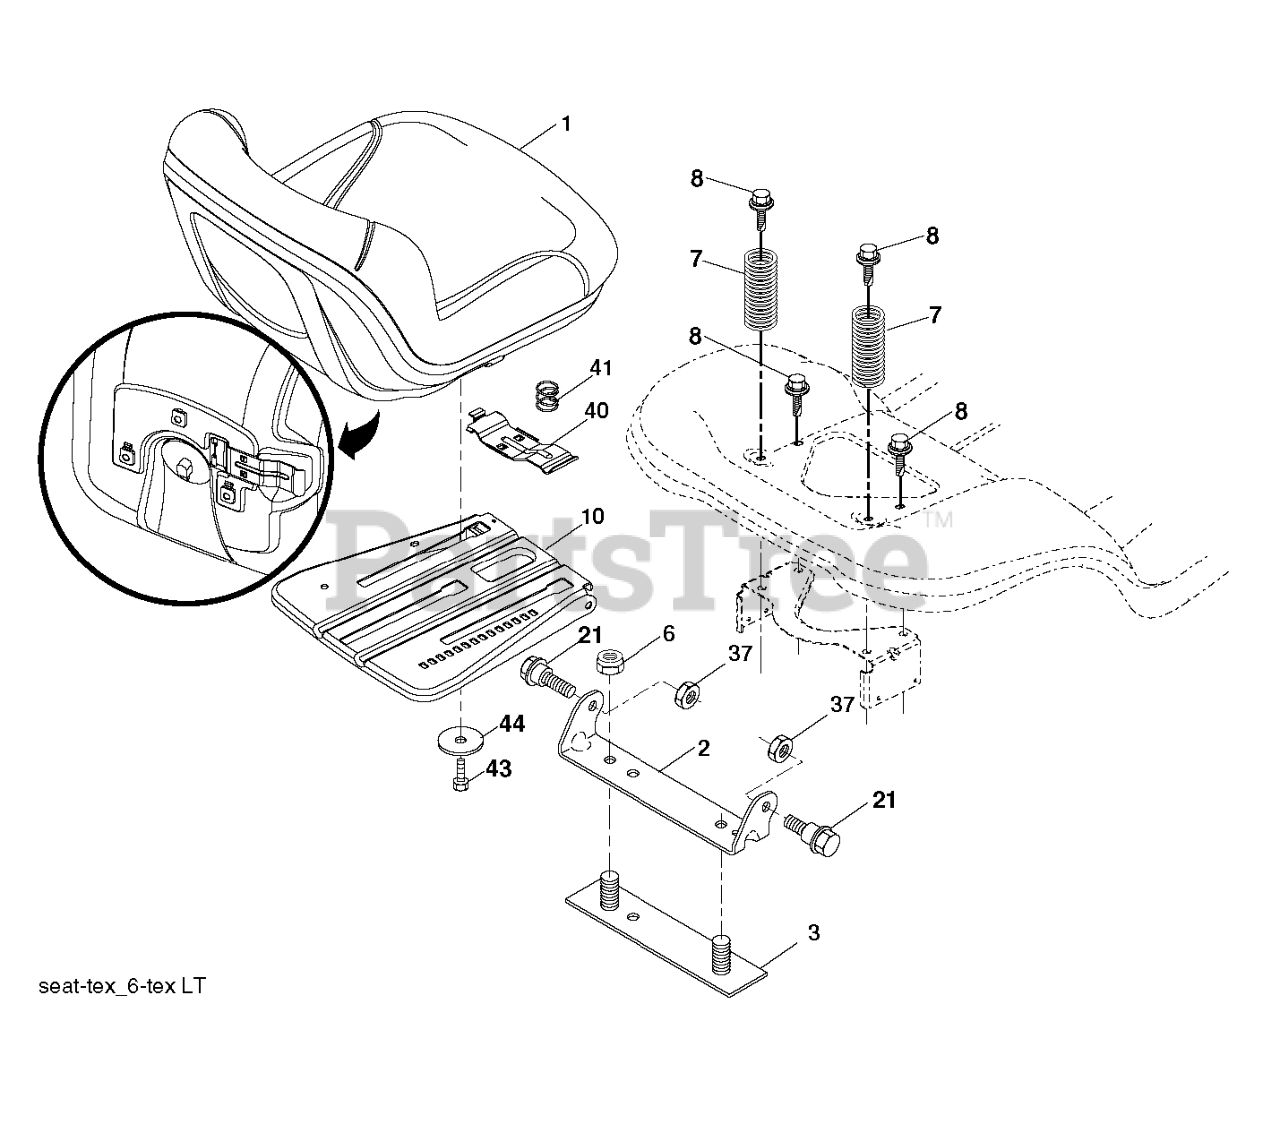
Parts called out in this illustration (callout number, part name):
1	RP SEAT.TH130.GRY.MILSCO.
2	BRKT.PIVOT.FENDER
3	STRAP
6	NUT
7	SPRING COMPRESSION
8	BOLT.5/16-18UNCX3/4 W/SEMS.BLK
10	PAN.ASM.SEAT.3PT
21	BOLT.SHOULDER.5/16-18
37	NUT.71038.31-18.HEX.NYLOCK
40	HANDLE.SLIDE.SEAT.TEX.BLACK
41	SPRING.LATCH.SEAT.TEX
44	WASHER 13/32 X 2-3/8 X 12GA
